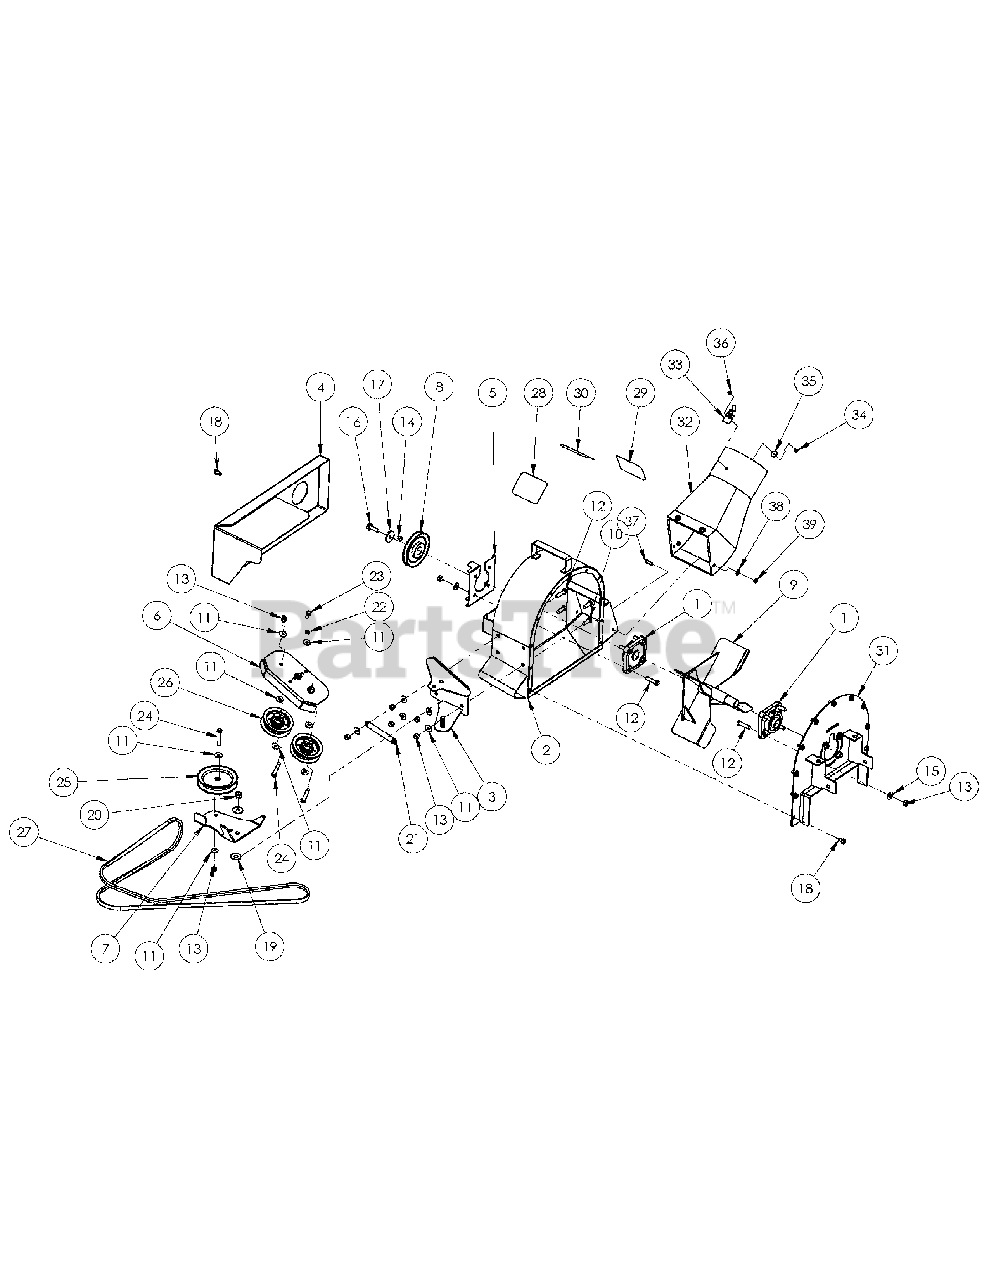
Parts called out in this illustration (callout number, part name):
2	15" VERTICAL BLOWER HOUSING
3	IDLER MOUNT W/A 15" BLOWER
4	EXTERIOR PULLEY COVER 15" BLOWER
5	5" BLOWER PULLEY BELT GUIDE
6	UPPER IDLER MOUNT PLATE
7	IDLER
8	DRIVE PULLEY
9	IMPELLER ASSEMBLY
10	CAP SCREW 3/8-16 X1 LONG
11	5/16" FLAT WASHER
12	CAP SCREW 3/8-16 X 1.50 LONG
13	3/8-16 NYLON INSERT NUT
14	KEY 1/4 SQ X .50 LONG
15	3/8 WASHER SAE
16	CAP SCREW SERATED FLANGE 3/8-16 X 1.25 LONG
17	FLAT WASHER,HEAVY
18	SELF-TAPPING SCREW 5/16 - ..625
19	1/2" FLAT WASHER
20	1/2-13 NYLON INSERT NUT
21	BELT DRIVE TENSION SPRING
22	5/16 LOCKWASHER
23	CAP SCREW 5/16-18 X .75 LONG
24	CAP SCREW 3/8-16 X 2.00 LONG
25	INSIDE IDLER
26	IDLER PULLEY, 3" HIGH FLANGE, 3/8" ID
27	BELT, 48" DECK
27	BELT, 60" DECK
28	THROWN OBJECT LABEL
29	TURN OFF MOWER LABEL
30	ROTATING BLADES LABEL
31	RECON BLOWER MOUNT
32	Transition Chute
33	SPRING CLIP
34	#10 x 3/4 SCREW
35	#10 FENDER WASHER
36	#10-24 Nylon Insert Nut
37	CAP SCREW -1/4-20 x .75 LONG
38	1/4" WASHER
39	1/4-20 Nylon Insert Nut
